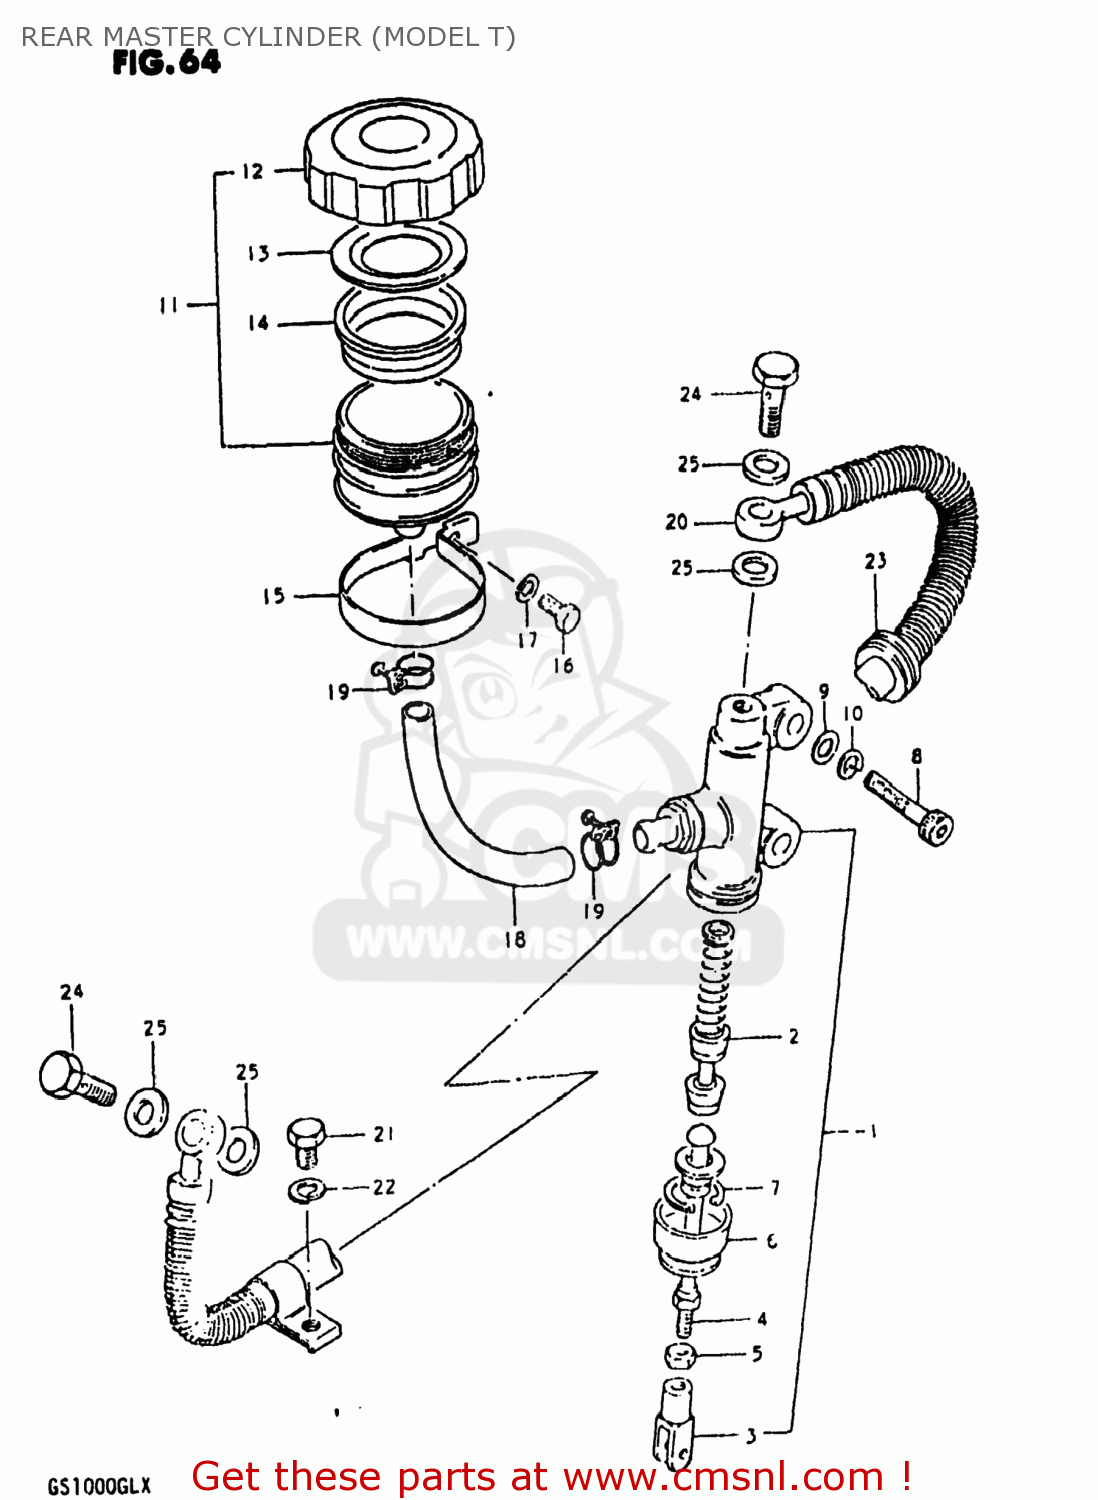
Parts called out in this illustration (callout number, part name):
1	CYLINDER ASSEMBLY,REAR MASTER
2	PISTON/CUP SET
3	YOKE
4	ROD,PUSH
5	NUT
6	BOOT
7	CIRCLIP
8	BOLT
9	WASHER
10	LOCK WASHER
11	TANK ASSEMBLY,RESERVOIR
12	CAP
13	PLATE,DIAPHRAGM
14	DIAPHRAGM
15	CLAMP
16	BOLT, UPPER
17	LOCK WASHER
18	HOSE,RESERVOIR TANK
19	CLAMP
20	HOSE,REAR BRAKE
21	BOLT
22	LOCK WASHER
23	GROMMET
24	BOLT,UNION
25	WASHER
